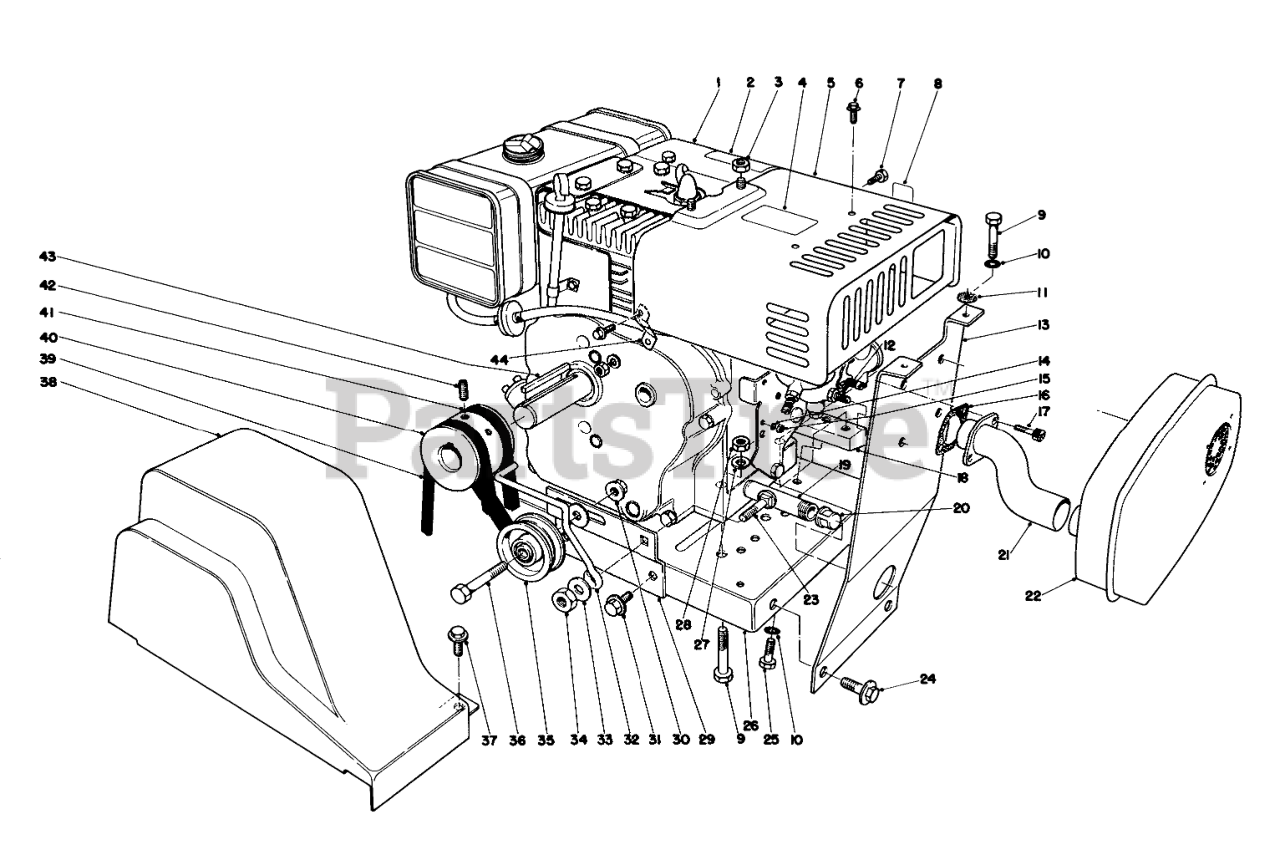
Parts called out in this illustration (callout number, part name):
1	Engine
2	CAUTION DECAL
3	NUT-HEX, SIDE DEFORM
4	Decal Hot Surface Warning
5	Heater Box
6	SCREW
8	CHOKE DECAL
9	SCREW-HH
10	WASHER-LOCK, INTERNAL
11	Washer
12	1/4-20 X 1/2 SEMS MS
13	Muffler Mounting Bracket
14	WASHER-LOCK/INT
15	NUT-LOCK
16	Gasket
17	SCREW-HSH
18	Block Engine Mounting
19	NIPPLE-PIPE
20	Pipe Cap
21	EXHAUST PIPE
22	Muffler
23	SCREW-CARR
24	SCREW-HH
25	SCREW-HH
26	Base-Engine
27	WASHER-PLAIN
28	NUT-LOCK, NI
29	Belt Idler Bracket
30	NUT-HHF, WHIZ
31	SCREW-HHFTF
32	BELT GUIDE
33	WASHER-FLAT
34	NUT-HEX
35	PULLEY B
36	SCREW-HH
37	SCREW-HWH
38	BELT GUARD
39	V-BELT
40	Pulley
41	V-BELT
42	Screw-Set
44	Brace Heater Box
